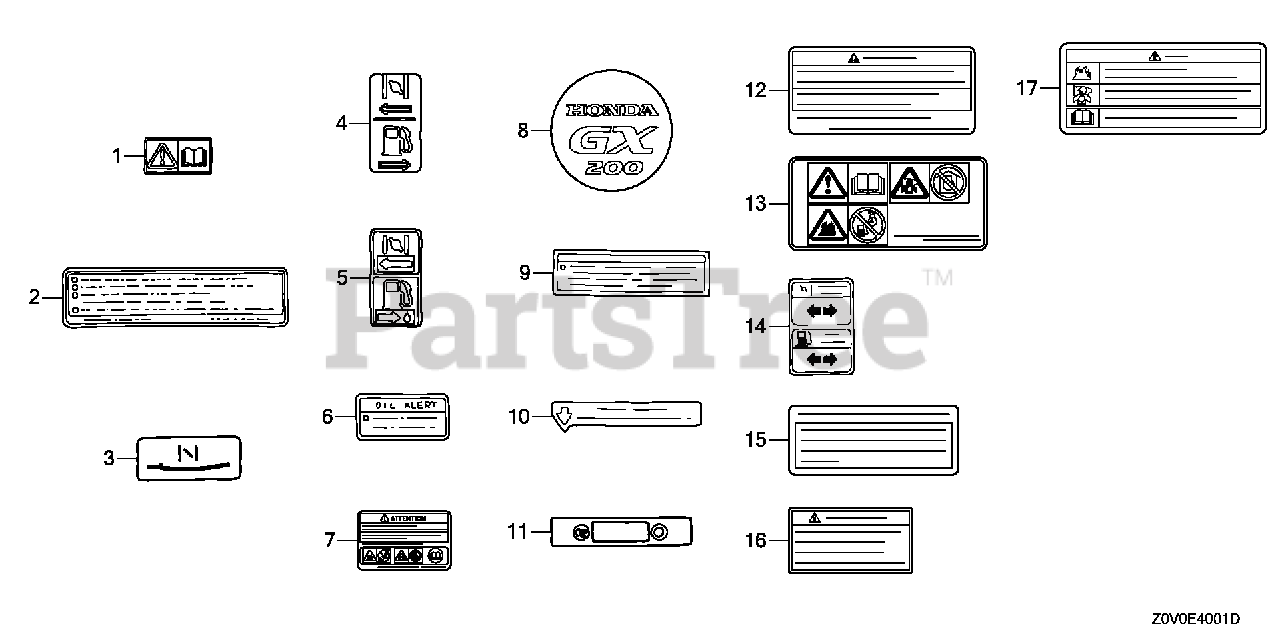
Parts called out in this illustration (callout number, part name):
1	MARK, OPERATOR CAUTION
2	LABEL, CAUTION
4	MARK, CHOKE
5	MARK, CHOKE (H=34)
6	MARK, OIL ALERT (ENGLISH)
